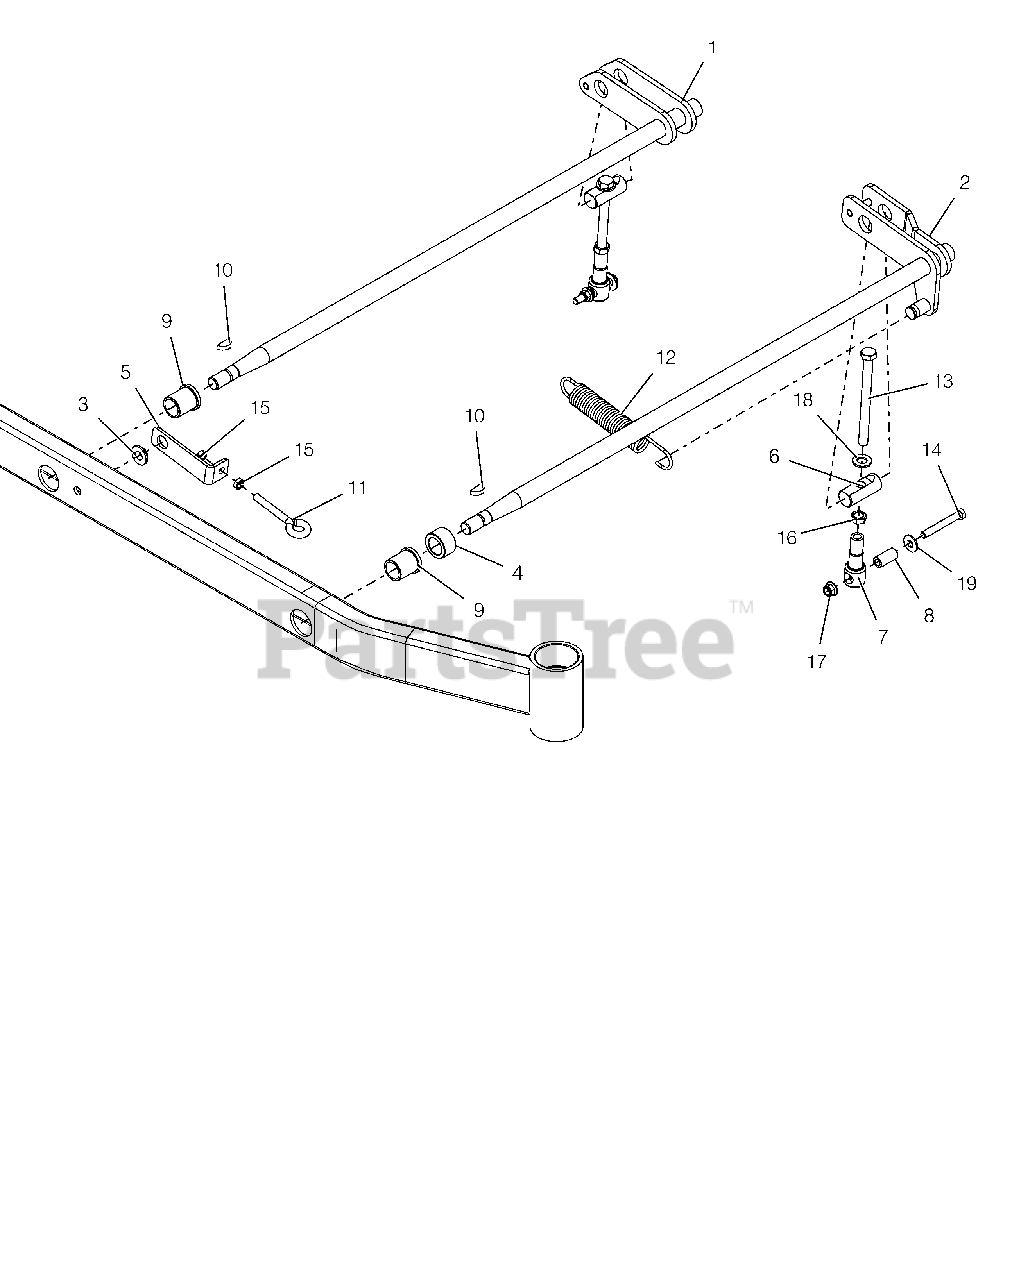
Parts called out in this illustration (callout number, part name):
1	REAR LH DECK LIFT ARM WMT- LF
2	FRT LH DECK LIFT ARM WMT- LF
3	BSHG-FLG .515X.750X.310X1.120
4	SPACER, 1.500 X 1.000 X .880
5	SPRING ANCHOR BRACKET - RED
6	PIN, DECK LIFT
7	LINK, DECK LIFT FORMED
8	SPACER, DECK LEVELING
9	BSHG-FLG 1.00X1.25X1.50X1.50
10	KEY-WDRF .25X1.00 HRD #15
11	BLT-EYE .375-16X2.50 YWZC
12	SG-TENS .162X1.25X8.25 WLD 25
13	BOLT,.50-13X6.00-2.50 LG THD
14	BLT-HEX .38-16X2.75 GR8 YWZC
15	NUT-HEX-JAM .375-16 YWZC
16	NUT-JAM .50-13 YWZC
17	@NUT-LK-NYL-FLG .38-16 YWZC
18	FLATWASHER 1/2 SAE HARD 15906
19	@WSHR-FL-STL.438X1.00X.083 YWZ
